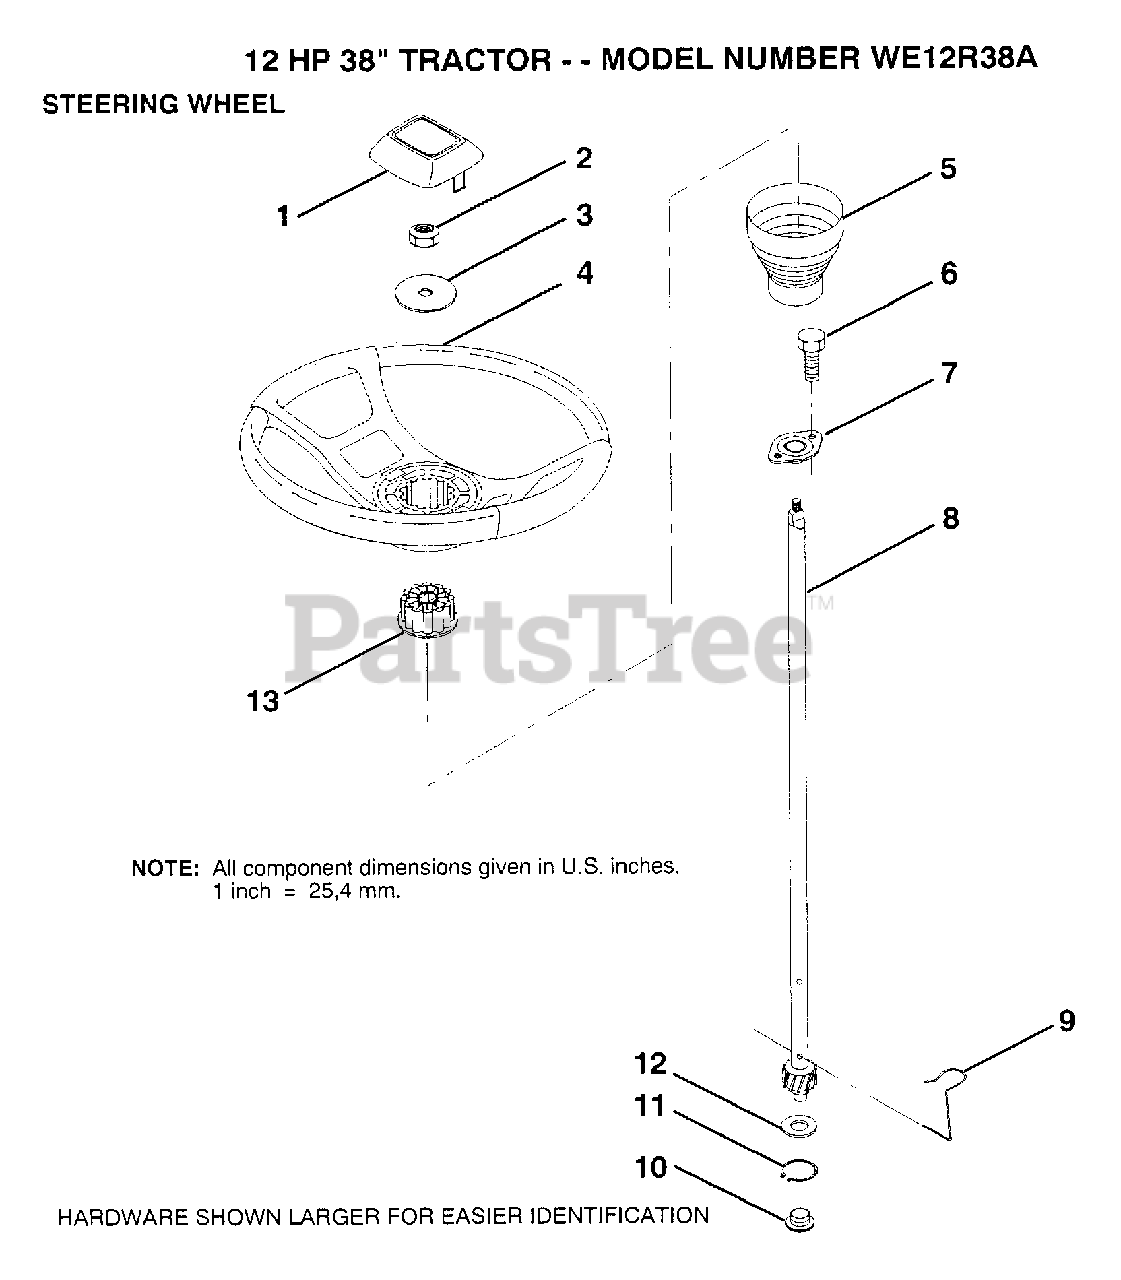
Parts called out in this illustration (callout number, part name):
1	ST WHL INSERT CAP
2	GRIPCO NUT
3	WASHER T
5	SLEEVE STEERING
9	STEERING CLIP
10	BUSHING STEER LWR
11	RING
12	WASHER LT
13	ADAPTER-WHEEL LT
